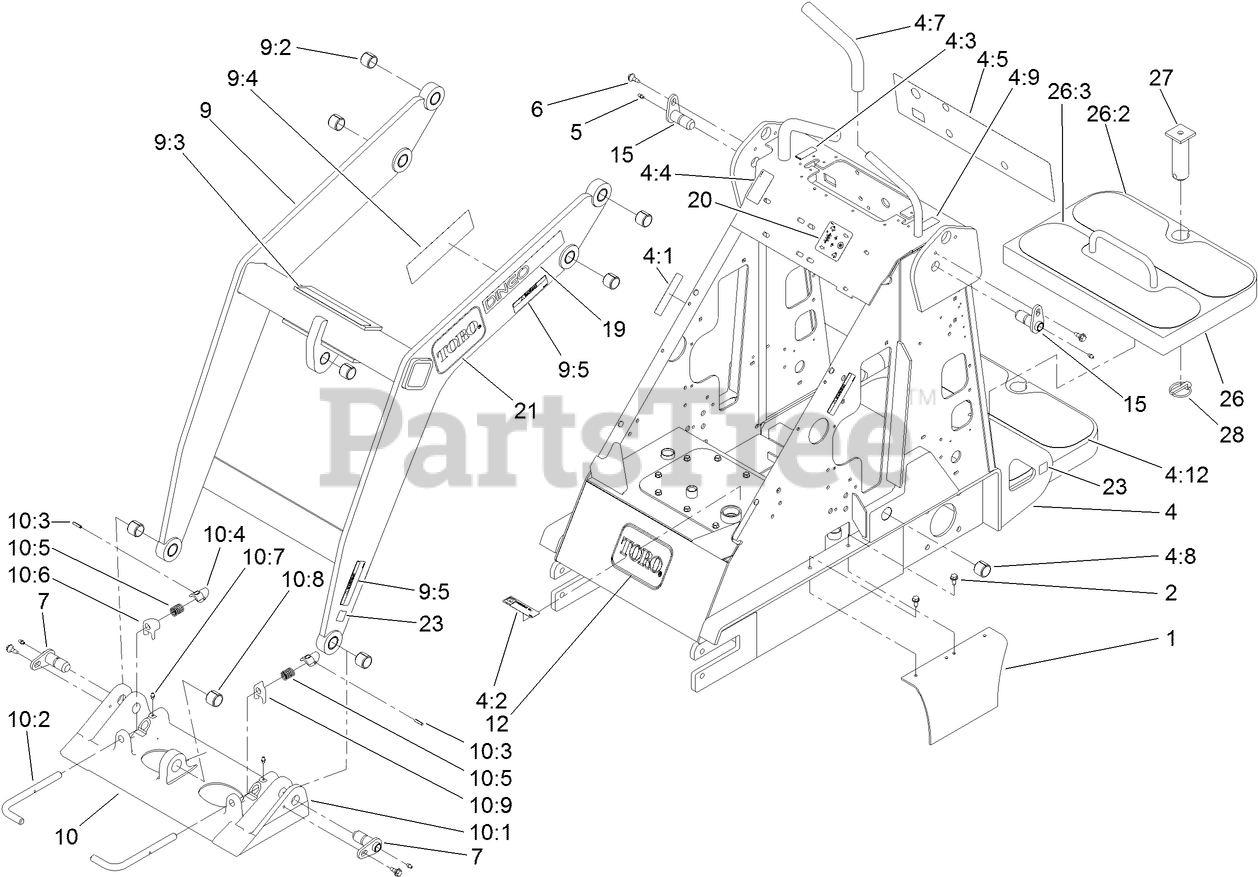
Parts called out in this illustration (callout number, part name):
1	COVER-CHAIN
2	SCREW-HWHTF
4	FRAME ASM
4:1	DECAL-PINCH
4:2	DECAL-OIL, HYD
4:3	DECAL-CHOKE
4:4	DECAL-POWER, AUXILIARY
4:5	DECAL-PANEL, CONTROL
4:7	GRIP-CUSHION
4:8	BUSHING-TENSION
4:9	DECAL-THROTTLE
4:12	TREAD-FOOT
5	FITTING-GREASE
6	BOLT-SHOULDER
7	PIN-PIVOT
9	LOADER ASM
9:2	BUSHING-TENSION
9:3	DECAL-CAUTION
9:4	DECAL-DANGER
9:5	DECAL-PINCH
10	QUICK ATTACH ASM
10:1	MOUNT-QTACH
10:2	PIN-LOCKING
10:3	PIN-GROOVED
10:5	SPRING-COMPRESSION
10:6	STOP-RH
10:7	FITTING-GREASE
10:8	BUSHING-TENSION
10:9	STOP-LH
12	DECAL
15	PIN-PIVOT
20	DECAL-SELECTOR, SPEED
21	DECAL
23	DECAL-POINT, LIFT
26	COUNTERWEIGHT ASM
26:2	TREAD-FOOT
28	PIN-LYNCH
